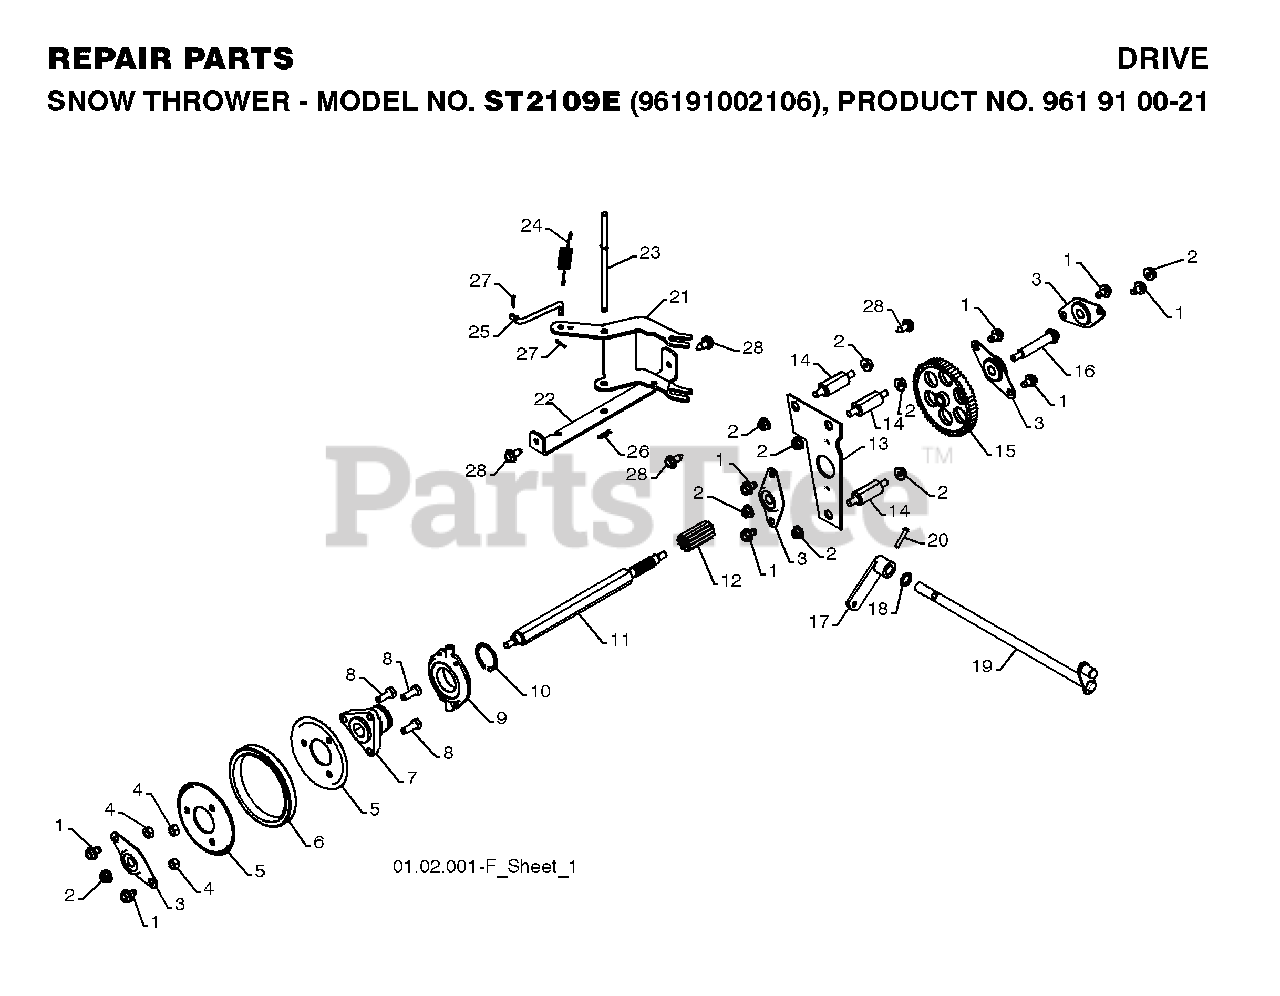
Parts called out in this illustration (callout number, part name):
1	SCREW LT
2	NUT, LOCK 5/16-18
3	BEARING, FLANGE
4	NUT.CENTERLOCK.5/16-
5	PLATE.RUBBER.WHEEL
6	RING, RUBBER WHEEL
7	HUB, RUBBER WHEEL
8	BOLT
9	TRUNNION BEARING ASSY
10	RETAINING RING
11	SHAFT.HEX.LONG
12	GEAR, PINION
13	AUXILLARY PLATE
14	SPACER, PLATE
15	GEAR, INTERMEDIATE
16	SHAFT, AUXILIARY
17	ARM, AUGER CONTROL
18	THRUST WASHER
19	CONTROL.SHAFT.ASM
20	CLEVIS PIN
21	LEVER.SHIFTER.PLATE.BLACK
22	BRACKET, PIVOT, SHIFT
23	PIN, PIVOT
24	SPRING, BIAS
25	LINK, SPEED CONTROL
26	RETAINER CLIP PM
27	RETAINER CLIP
28	BOLT.HEX.HD.WASHER.5/16-18X.75
